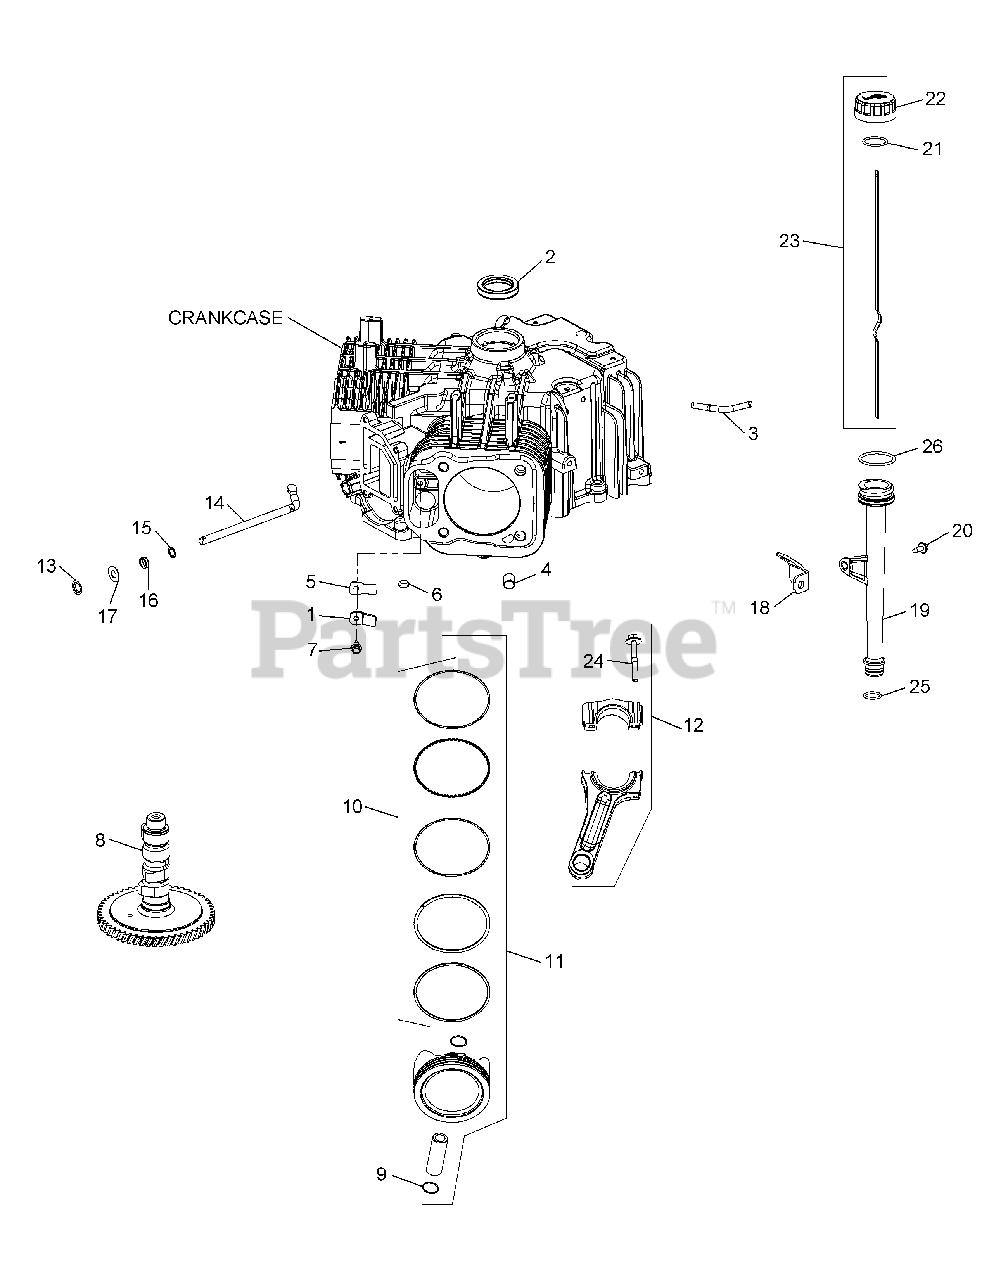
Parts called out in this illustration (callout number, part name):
1	Breather Reed Retainer
5	Breather Reed
7	Flange Screw, M5 x 0.8 x 10
8	Camshaft Kit
9	Piston Pin Retainer
10	Piston Ring Set (STD)
10	Piston Ring Set (.08)
10	Piston Ring Set (.25)
10	Piston Ring Set (.50)
11	Piston Kit w/ Ring (STD) (Inc. 9 & 10)
11	Piston Kit w/ Ring (.08)
11	Piston Kit w/ Ring (.25)
11	Piston Kit w/ Ring (.50)
12	Connecting Rod Kit (Inc. 24)
13	Ring Retainer
14	Governor Cross Shaft
15	Flat Washer, 11/32"
16	Governor Cross Shaft Seal
17	Flat Washer, 9 mm
18	Oil Fill Tube Bracket
19	Oil Fill Assembly Tube
20	Flange Screw, M5 x 0.8 x 13
21	Dipstick O-Ring
22	Oil Fill Cap Kit (Yellow)
23	Dipstick, Assembly (Inc. 21 & 22)
24	Connecting Rod Bolts Kit
25	Lower Oil Fill Tube O-Ring
26	Upper Oil Fill Tube O-Ring
